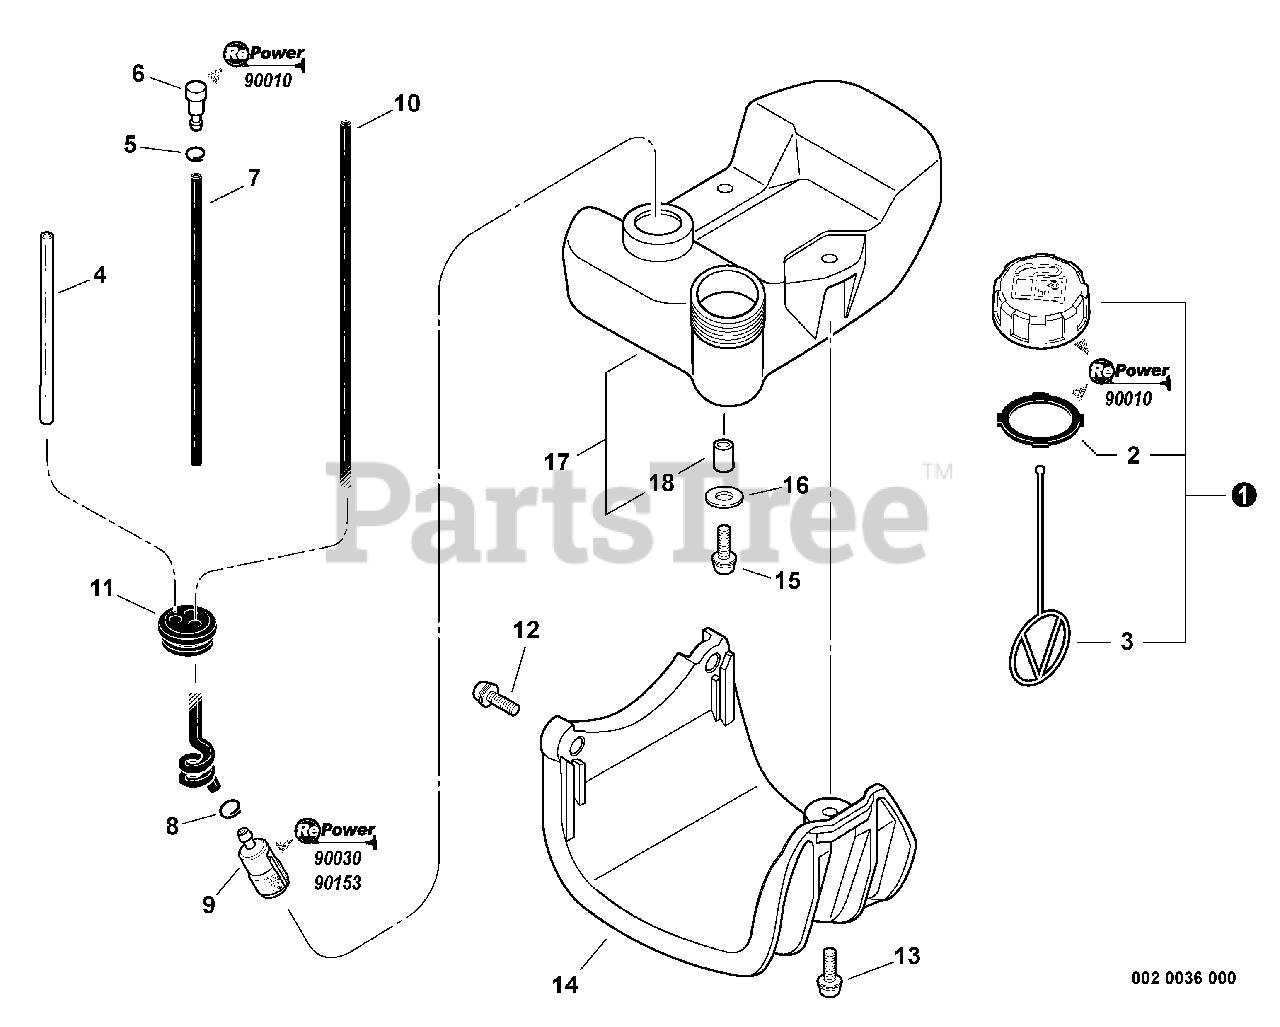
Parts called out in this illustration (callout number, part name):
1	CAP ASSY, FUEL
2	GASKET, FUEL CAP
3	CONNECTOR, CAP L= 100 MM
4	PIPE, FUEL 3×6×80 CLEAR
5	CLIP Ø6.5 MM
6	VENT ASSY
7	PIPE 3×6×115 BLACK
8	CLIP Ø6.5 MM
9	FILTER, FUEL
10	PIPE, FUEL 3×6×165
11	GROMMET, FUEL
12	BOLT 5×22
13	SCREW 5×20
14	GUARD, FUEL TANK
15	BOLT 5×16
16	WASHER 5.5×12×0.8
17	TANK, FUEL
18	SPACER 6.2×7.8×6
19	CAP/VENT KIT - REPOWER
20	REPOWER FILTRATION KIT
21	TUNE-UP KIT
